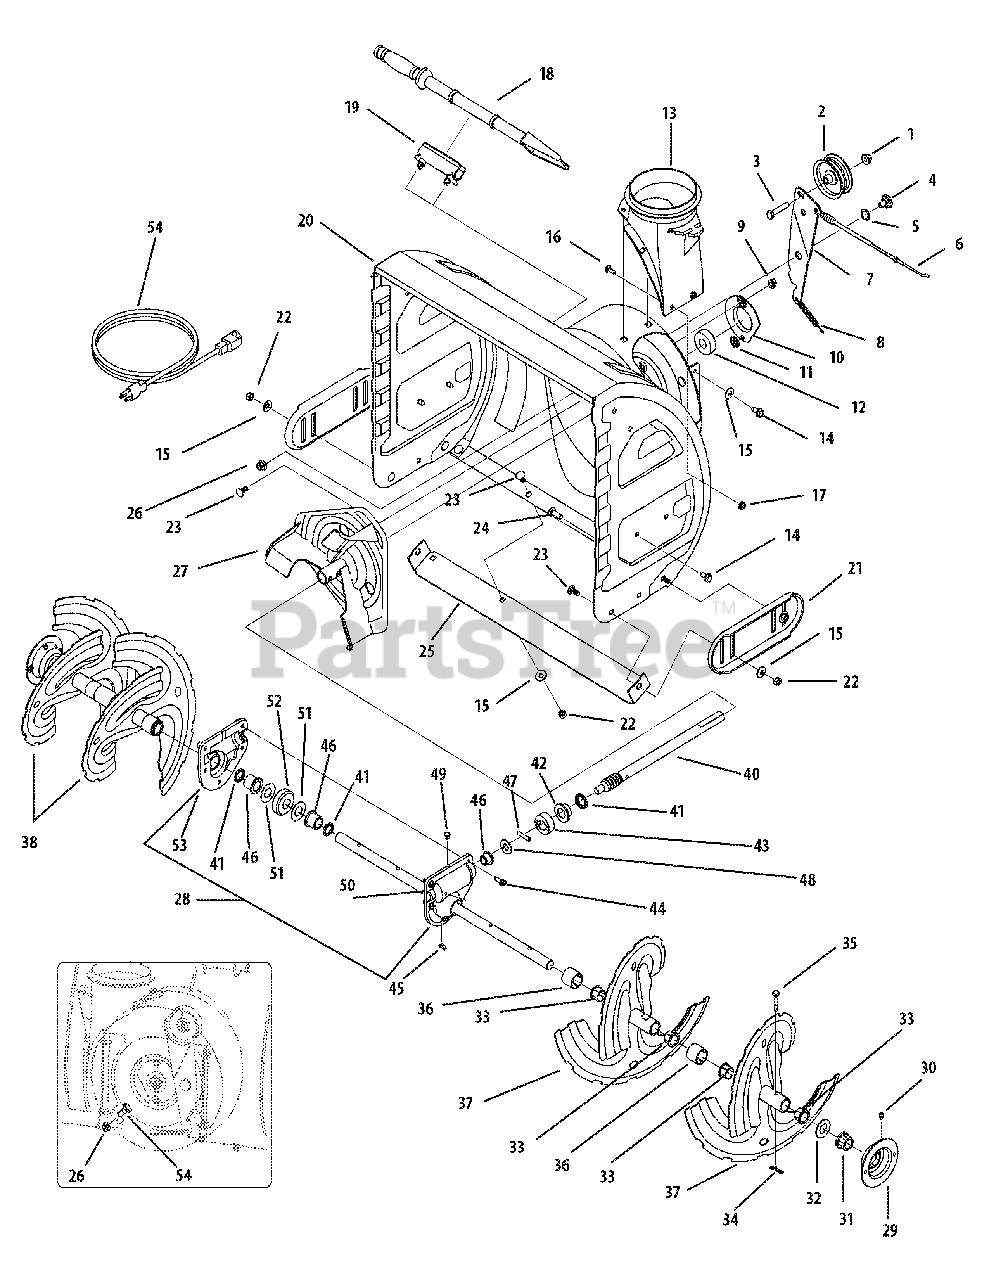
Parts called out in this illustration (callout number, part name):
1	Flange Lock Nut, 3/8-16
2	Flat Pulley, 2.75 OD
3	Hex Screw, 3/8-16 x 1.75
4	Shoulder Screw, 3/8-16 x .625 x .17
5	Wave Washer, .625 x .885 x .0175
6	Auger Drive Cable
7	Auger Idler Bracket
8	Extension Spring, .38 OD x 4.59
9	Flange Lock Nut, 1/4-20
10	Bearing Housing, 1.85 ID
11	Push-On Nut, .25 Dia.
12	Flange Ball Bearing, .75 ID x 1.85 OD
13	Chute Adaptor, 5" Dia.
14	Hex washer screw, 5/16-18 x .750
15	Bell Washer, .340 x .872 x .060
16	Carriage Screw, 1/4-20 x .75
17	Flange Lock Nut, 1/4-20
18	Cleanout Tool
19	Cleanout Tool Mount
20	Auger Housing, 26" Cub
21	Skid Shoe, stainless
22	Hex Nut, 5/16-18
23	Carriage Bolt, 5/16-18 x .750
24	Carriage Screw, 5/16-1x 1.00
25	Shave Plate, 26"
26	Flange Lock Nut, 3/8-16
27	Impeller Assembly, 12" Dia.
28	Gear Box Assembly, 26"
29	Bearing Housing, 1" hex
30	Drive Lube Fitting, 3/16
31	Hex Flange Bearing x .75 ID
32	Flat washer, .76 x 1.49 x .06
33	Flange Bushing, .800 ID x .910 OD
34	Bow-Tie Cotter Pin
35	Shear Pin, .25 x 1.50
36	Spacer, 1.25OD x .75ID x 1.00
37	Spiral Assembly (Left)
38	Spiral Assembly (Right)
39	Extension Cord
40	Worm Shift, .75 OD
41	Oil Seal, .75 x 1.131 x .188
42	Flange Bearing, .50 ID x .75 OD x .59
43	Thrust Collar, .756 ID x .600
44	Hex Washer Screw, 1/4-20 x .750
45	Hi-Pro Key, 3/16 x 5/8
46	Flange Bearing, .50 ID x .75 OD x .59
47	Dowel Pin, .25OD x 1.25
48	Flat Washer, .51 x 1.12 x .06
49	Plug, 1/4 x .437
50	Housing Assembly with Fitting
51	Flat Washer, .760 ID x 1.50 OD
52	Worm Gear
53	Housing Assembly
54	Shoulder Bolt, 3/8-16 x .496 x .336
